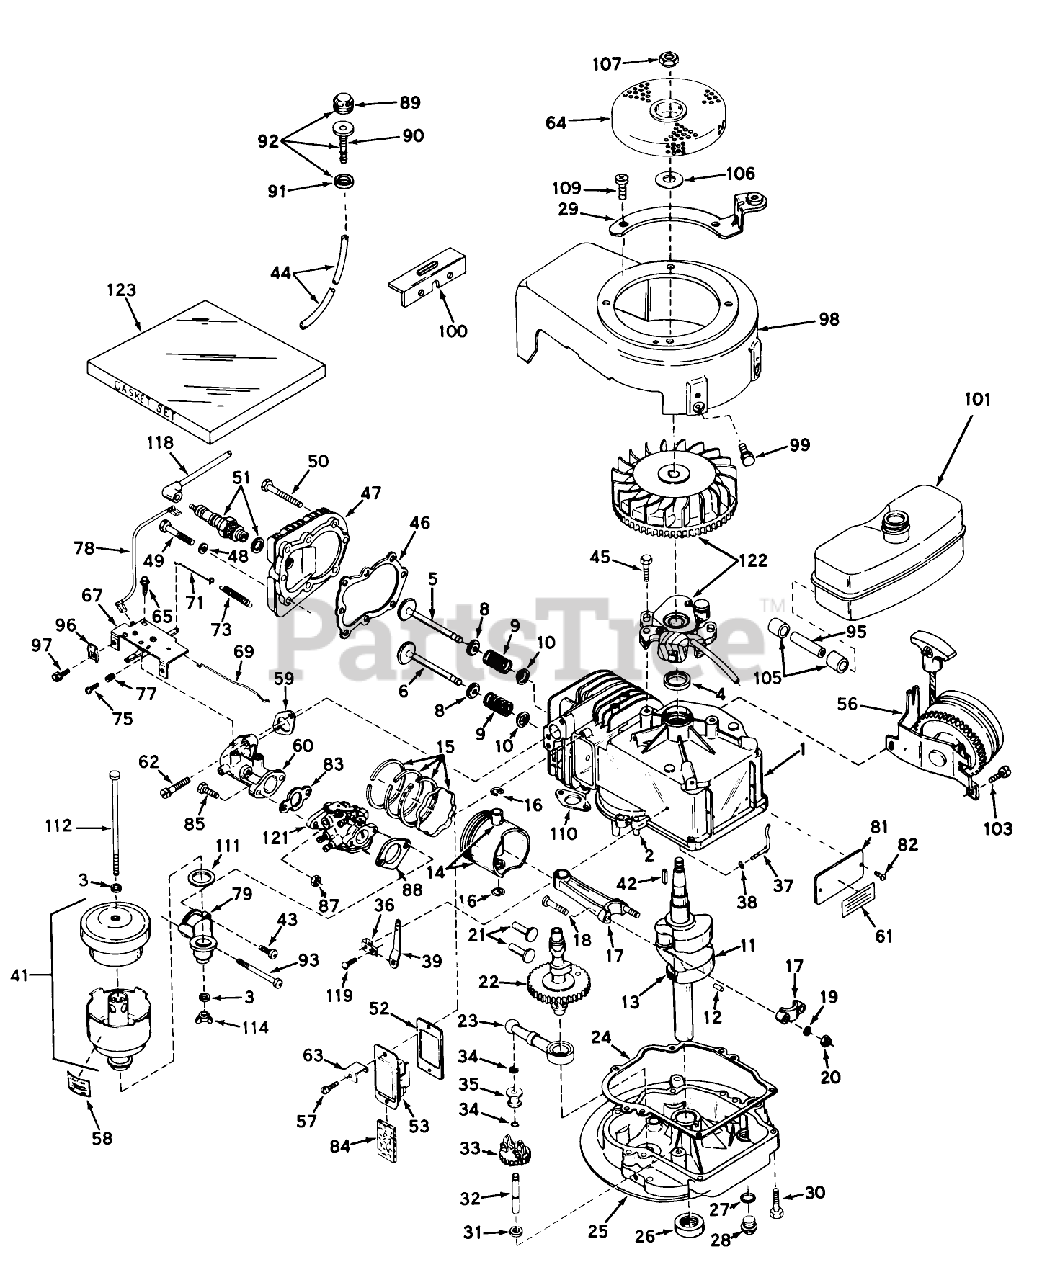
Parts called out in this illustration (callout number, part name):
1	Cylinder Assy. (Incl. Ref. 2 4)
2	Pin-Dowel
3	Washer Fibre
4	OIL SEAL
5	Valve, Intake (Incl. Ref. #38, 39 40) (Std.)
5	Valve, Intake(1/32"overs.)(Incl. Ref. 8, 9 10)
6	Valve, Exhaust (Standard)(Incl. Ref. 8, 9 10)
6	Valve, Exhaust (1/32" Overs.(Incl. Ref. 8, 9 10)
8	Cap-Upper Valve Spring
9	Spring-Valve
10	Cap-Valve, Spring
11	Crankshaft Assy. (Incl. Ref. 12 13)
12	Pin, Groove
13	Gear, Crankshaft
14	Piston Pin Assy. (Standard)(Incl. 2 of No. 16)
14	Piston Pin Assy. (.010 overs.)(Incl. 2 of Ref. 16)
14	Piston Pin Assy. (.020 overs.)(Incl. 2 of Ref. 16)
15	Ring Set, Piston (Std.)
15	Ring Set, Piston (.010 o.s.)
15	Ring Set, Piston (.020 o.s.)
16	Ring-Retaining, Piston Pin
17	Rod Assy., Connecting (Incl. Nos. 18, 19 20)
18	Bolt, Connecting
19	Washer
20	LOCKNUT
21	Lifter-Valve
22	Camshaft
23	Oil Pump ASM
24	Gasket, Mounting
25	Flange Assy., Mounting (Incl. Ref. 26, 27, 28 32)
26	Seal Oil
27	Gasket-Oil Drain
28	Plug Oil Drain
29	Bracket Assy., Starter
30	Screw (1/4-20 x 1-1/4)
31	Washer-Flat
32	Shaft-Governor
33	Governor Gear ASM
34	Ring-Retaining
35	Spool-Governor
36	Clamp-Lever, Governor
37	Rod, Governor (Incl. No. 36)
38	Washer-Flat
39	Lever, Governor
41	Cleaner Assy., Air
42	Key Flywheel
43	KIT - SEAL WIPER
44	Beam Assy.
45	Screw
46	Gasket-Cylinder Head
47	CYLINDER HEAD
48	Washer
49	Screw
50	Screw
51	SPARK PLUG
52	Gasket Breather
53	Breather Assembly (Incl. Nos. 52 84)
56	Starter, Side Mount Rewind
57	Screw
58	Decal, Air Cleaner
59	Gasket, Intake
60	Pipe, Intake
61	480B GIL SNWTHWR O/
62	Screw, Fil. Hd. Sems
63	Retainer Clip
64	Screen, Flywheel
65	Screw (10-24 x 9/16)
67	Control Assy., Speed (Incl. Nos. 161 162)
69	Link, Throttle to Governor
71	Link, Governor Spring
73	Spring, Governor
75	Screw
77	Spring-Compression
78	Wire, Ground
79	Elbow, Air cleaner
81	IDENTIFICATION PLATE
82	Stud
83	Gasket-Carburetor
84	Element-Breather
87	Nut and Lock Washer (1/4-28)
88	Gasket
89	Bulb, Primer
90	Body, Primer
91	Retainer, Primer Bulb
92	Primer Assy. (Incl. Nos. 89, 90 91)
93	Screw
95	Line, Fuel
96	Conduit
97	Screw (10-32 x 3/8)
98	Housing, Blower
99	Screw (1/4-20x19/32)
100	Bracket, Shroud
101	Tank, Fuel
103	Screw, Fil. Hd. Sems
105	Line-Fuel (8.62)
106	Washer
107	Hex Nut
109	Screw
110	Gasket Exhaust
111	Gasket, Spacer
112	Bolt, Air Cleaner
114	Nut, Wing
118	Cover-Spark Plug
119	Screw
121	Carburetor
122	Magneto
123	Gasket Set
